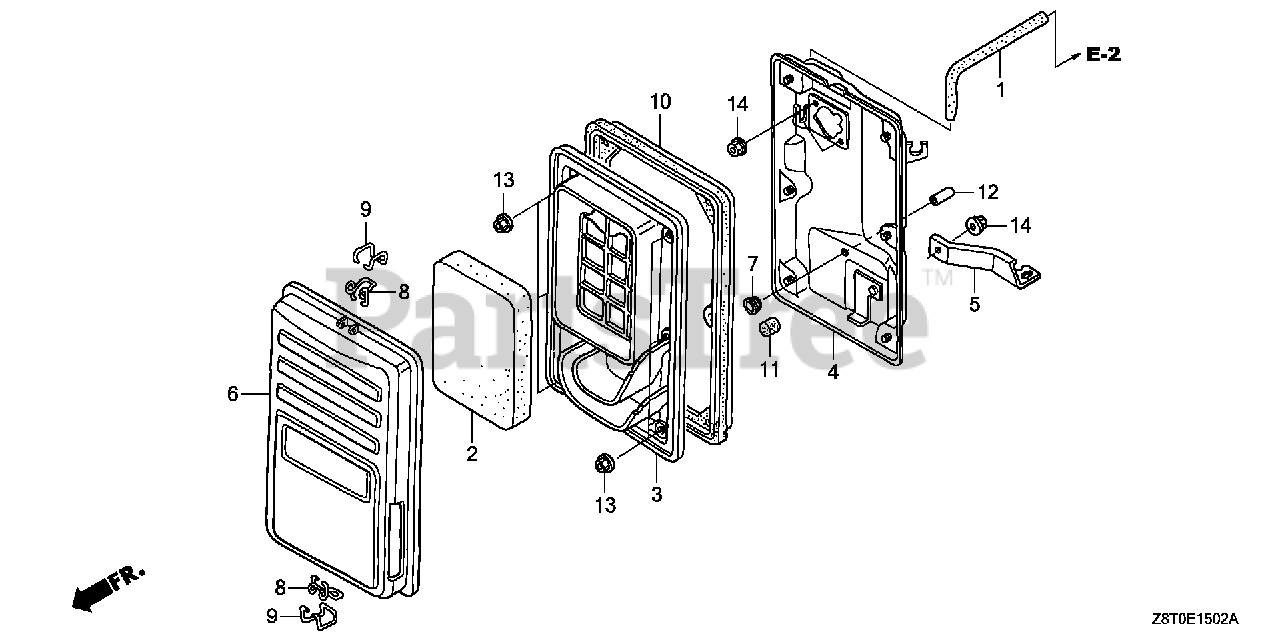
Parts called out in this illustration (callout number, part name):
1	TUBE, BREATHER
2	ELEMENT, AIR CLEANER
3	SEPARATOR, AIR CLEANER
4	HOUSING, AIR CLEANER
5	STAY, AIR CLEANER
6	COVER, AIR CLEANER
7	GROMMET, AIR CLEANER
8	CLIP A, AIR CLEANER WIRE
9	CLIP B, AIR CLEANER WIRE
10	SEAL, AIR CLEANER
11	FILTER, DRAIN TUBE
12	CAP, SEALING
13	NUT, FLANGE (5MM)
14	NUT, FLANGE (6MM)
